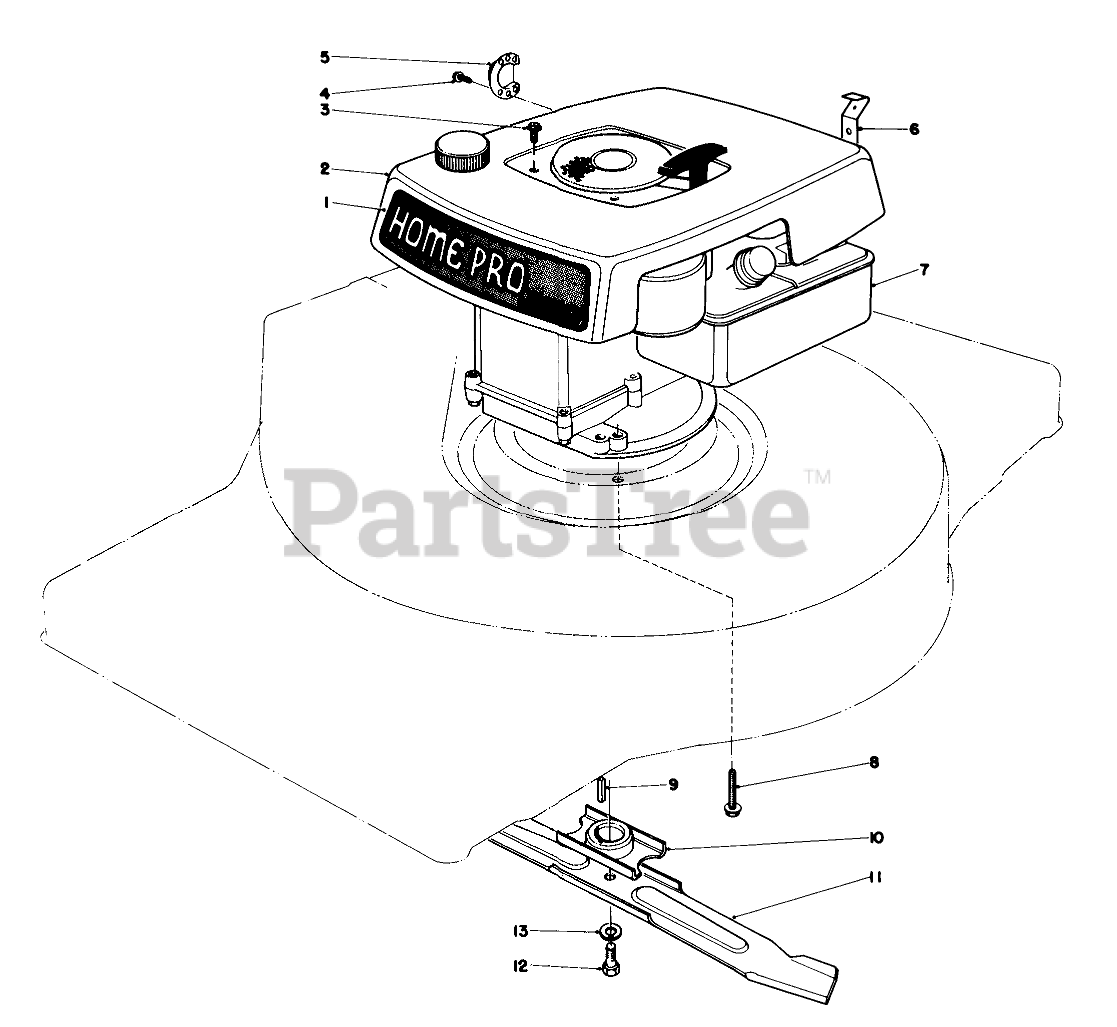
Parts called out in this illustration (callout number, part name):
1	Decal Shroud
2	Shroud
3	8X1/2 SELF TAP SCREW
4	SCREW W/ENGINE
5	Deflector
6	Bracket Control
7	Engine
8	SCREW-HWHTF
9	KEY-SQUARE
10	Blade Retailer
11	Blade
12	SPECIAL SCREW
13	WASHER-LOCK
